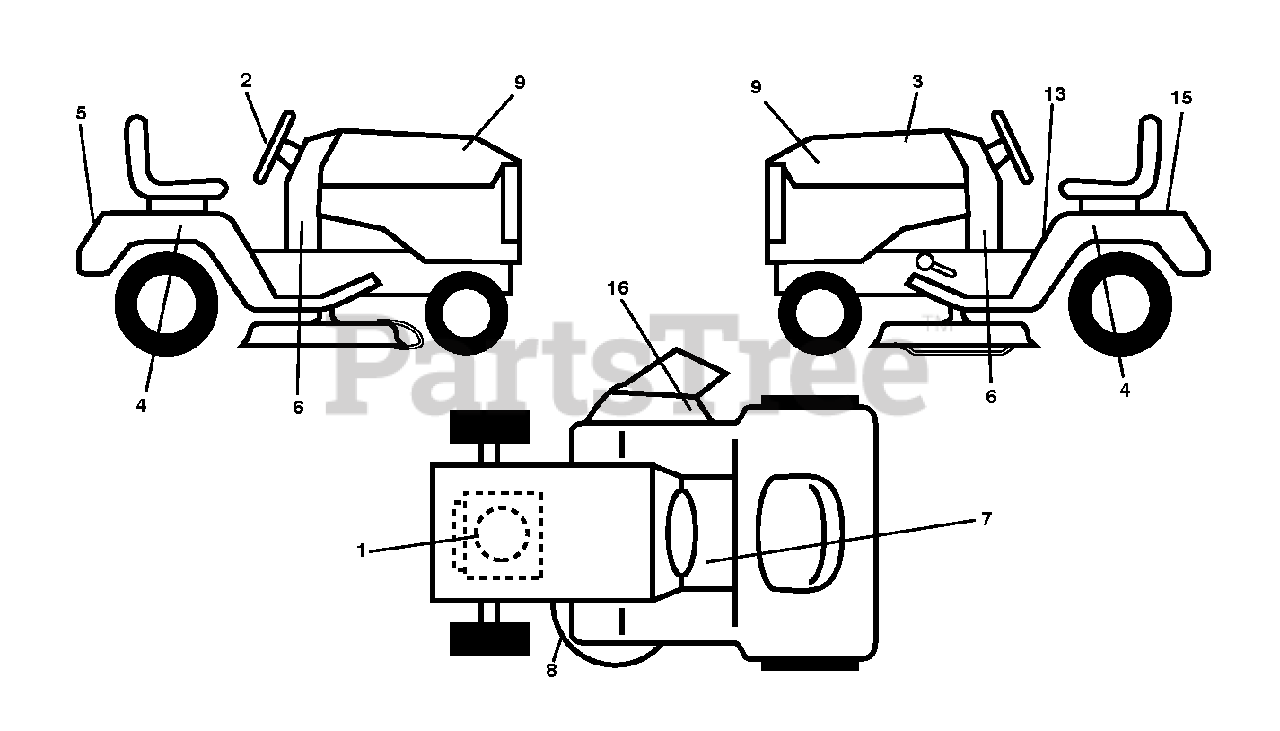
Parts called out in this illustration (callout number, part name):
1	DECAL.ENG.BS.5HP.PB.278978
2	DECAL.WHEEL.STRG.STDHRS.POULAN
3	DECAL.RPL.PMST.42C.BS.175.STL
4	DECAL.FEND.RH/LH.SET.6S.POULAN
5	DECAL.FEND.POULAN.2010
6	DECAL.DASH.LWR.17.5/42.POULAN
7	DECAL, WARNING SPARK ARRESTOR
8	DECAL V BELT SCHEMATIC
9	DECAL.HOOD.ALPHA.RH/LH.POULAN
13	Fender Warning Decal, English
15	DECAL BTRY SYMBOLS
16	DECAL.WARN.KEEP.HAND.AWAY
